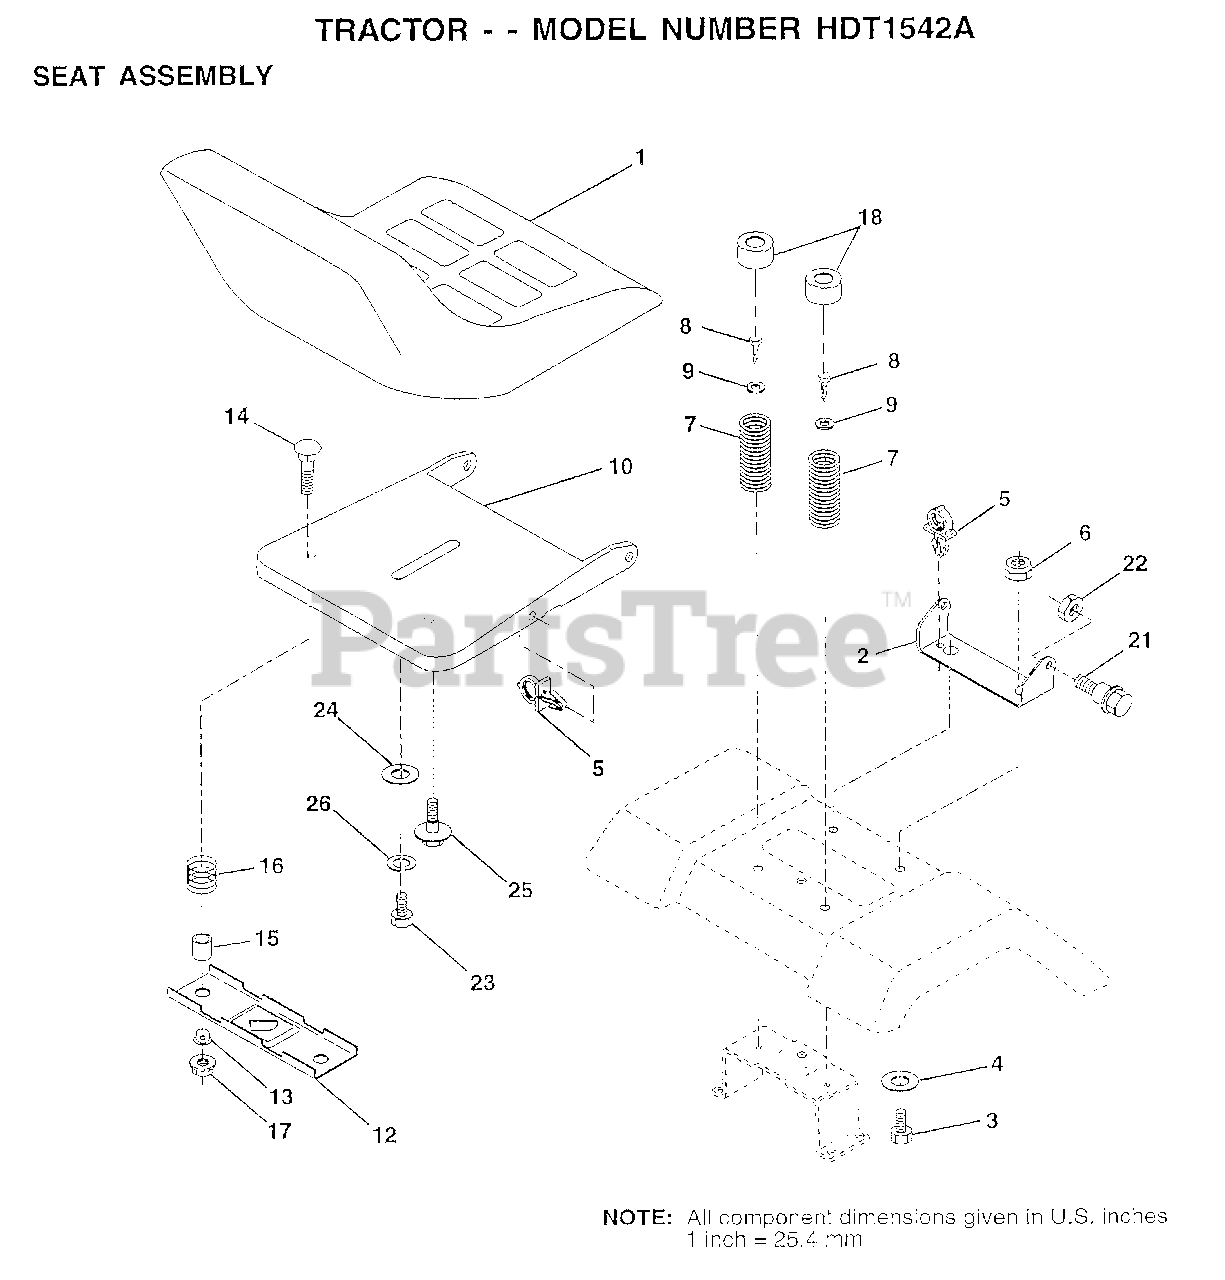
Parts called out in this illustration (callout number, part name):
1	SEAT
2	BRACKET PVT SEAT
3	BOLT
4	WASHER PM
5	CLIP.PUSH-IN.HING
6	NUT
7	SPRING COMPRESSIO
8	SCREW
9	WASHER
10	PAN-SEAT
12	BRKT SWITCH
13	BUSHING
14	BOLT-RD HD SQ NK
15	SPLIT SPACER
16	SPRING
18	CAP SPRING
21	"BOLT,SHOULDER"
23	BOLT
24	WASHER
25	"BOLT,SHOULDER"
26	LOCKWASHER
